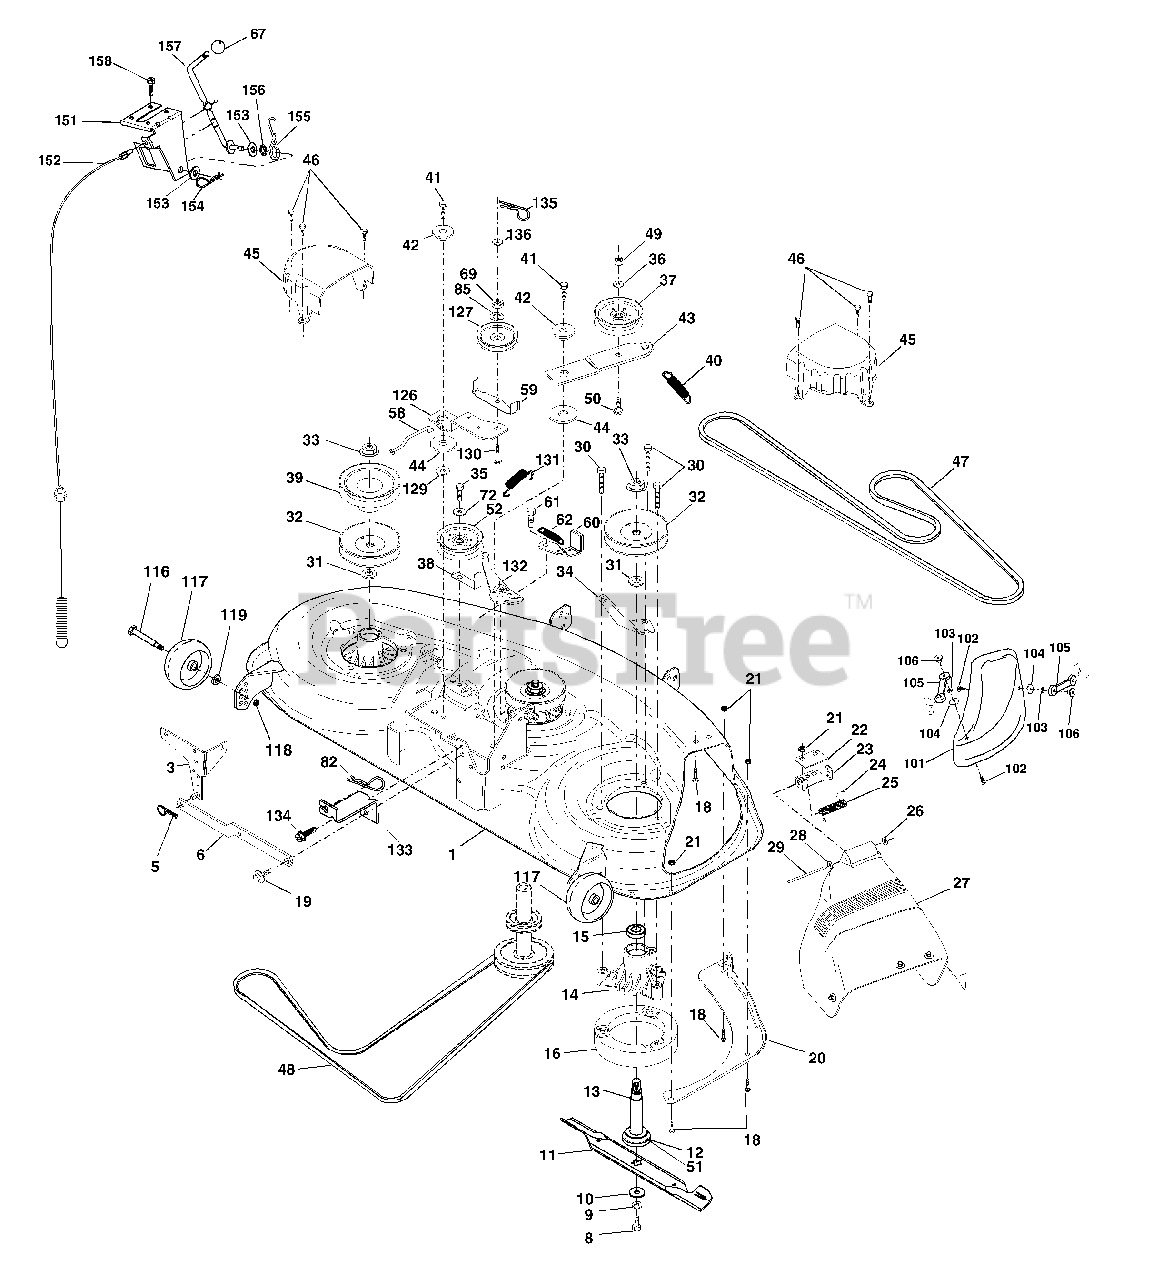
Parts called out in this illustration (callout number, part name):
1	Deck Asm., Mower 46"
3	Bracket Asm., Sway Bar
5	Retainer Spring
6	Arm, Suspension, Rear (Sway Bar)
8	Bolt, Patched 3/8-24 x 1-1/4 Gr. 8
9	Washer, Lock Hvy., Unplated 3/8
10	Washer, Hard Blade, Mower Vented
11	Blade Hi-Perf 46"
12	Bearing, Ball, Mandrel #6204
13	Shaft Asm. w/Lower Bearing
14	Housing, Mandrel
15	Bearing, Ball, Mandrel
16	Stripper, Mower Round
18	Bolt, Carriage 5/16-18 x 5/8
19	Bolt, Hex Head, Shoulder 5/16-18
20	Baffle, Vortex Mower 46"
21	Nut, Crownlock 5/16-18 UNC
22	Stiffiner, Bracket
23	Bracket, Deflector
24	Cap, Sleeve
25	Spring, Torsion, Deflector
26	Nut, Push
27	Shield, Deflector Mower
28	Washer 11/32 x 5/8 x 16 Ga.
29	Rod, Hinge
30	Screw, Thdroll Washer Head
31	Washer, Spacer Mower Vented
32	Pulley, Mandrel
33	Nut, Flg. Top Lock Cntr. 9/16
34	Anchor, Spring Deck 46"
35	Screw, Thdroll 3/8-16 x 1-3/4 Tytt
37	Pulley, Idler, Flat
38	Keeper, Belt, Idler
39	Pulley, Idler, Driven
40	Spring, Secondary 44/46/50 Vent
41	Screw 3/8-16 x 1-1/4
42	Spacer, Retainer
43	Arm, Idler Secondary
44	Washer, Hardened
45	Cover, Mandrel Deck
46	Screw, Thdroll. 1/4-20 x 5/8
47	V-Belt, Mower, Secondary
48	V-Belt, Mower, Primary
49	Nut, Crownlock 3/8-16 UNC
50	Bolt, Carriage 3/8-16 x 1-1/2 Gr. 5
51	Washer Felt
52	Pulley Idler Flat
58	Rod Brake 46"
59	Guide Bolt 46" Mower Dr
60	Arm Asm Brake 46"
61	Bolt Shld 5/16-18
62	Spring Return
67	Knob Rd 3/8-16 Plstc Thds Blk
69	Nut Hex Jam 3/8-16 Unc
72	Washer 13/32 x 1 x 16 Ga.
82	Retainer Spring
85	Washer Lock 3/8
101	Cover Mulcher 46" Black
102	Screw Truss Hd Phil 10-24 x 5/8
103	Washer Lock #10
104	Washer #10
105	Latch Asm Bagger
106	Nut Weld .327/.304 #10-24
116	Bolt, Shoulder
117	Gauge Wheel
118	Nut, Centerlock 3/8-16 UNC
119	Washer 3/8 x 7/8 x 14 Ga.
126	Arm, Idler, Primary Deck 46"
127	Pulley, Idler, V-Groove Dim. 4.25
129	Washer 13/32 x 2-3/8 x 8 Ga
130	Bolt Carriage Idler
131	SPring Return Idler
132	Arm Spring Brake Mower
133	Bracket Anchor Cable 46"
134	Screw Thdrol 5/16-18 x 3/4
135	Retainer Spring Yellow
136	Washer 9/32 x 3/4 x 16 Ga
151	Bracket Clutch Cable
152	Clutch Cable 38"/46"
153	Washer Flat 3/8" Type B
154	Spring Retainer
155	Spring Retension Q
156	SPacer Clutch Cable
157	Rod Clutch Cable 3/8"
158	Screw Hex Thd Cut 1/4-20 x 5/8
